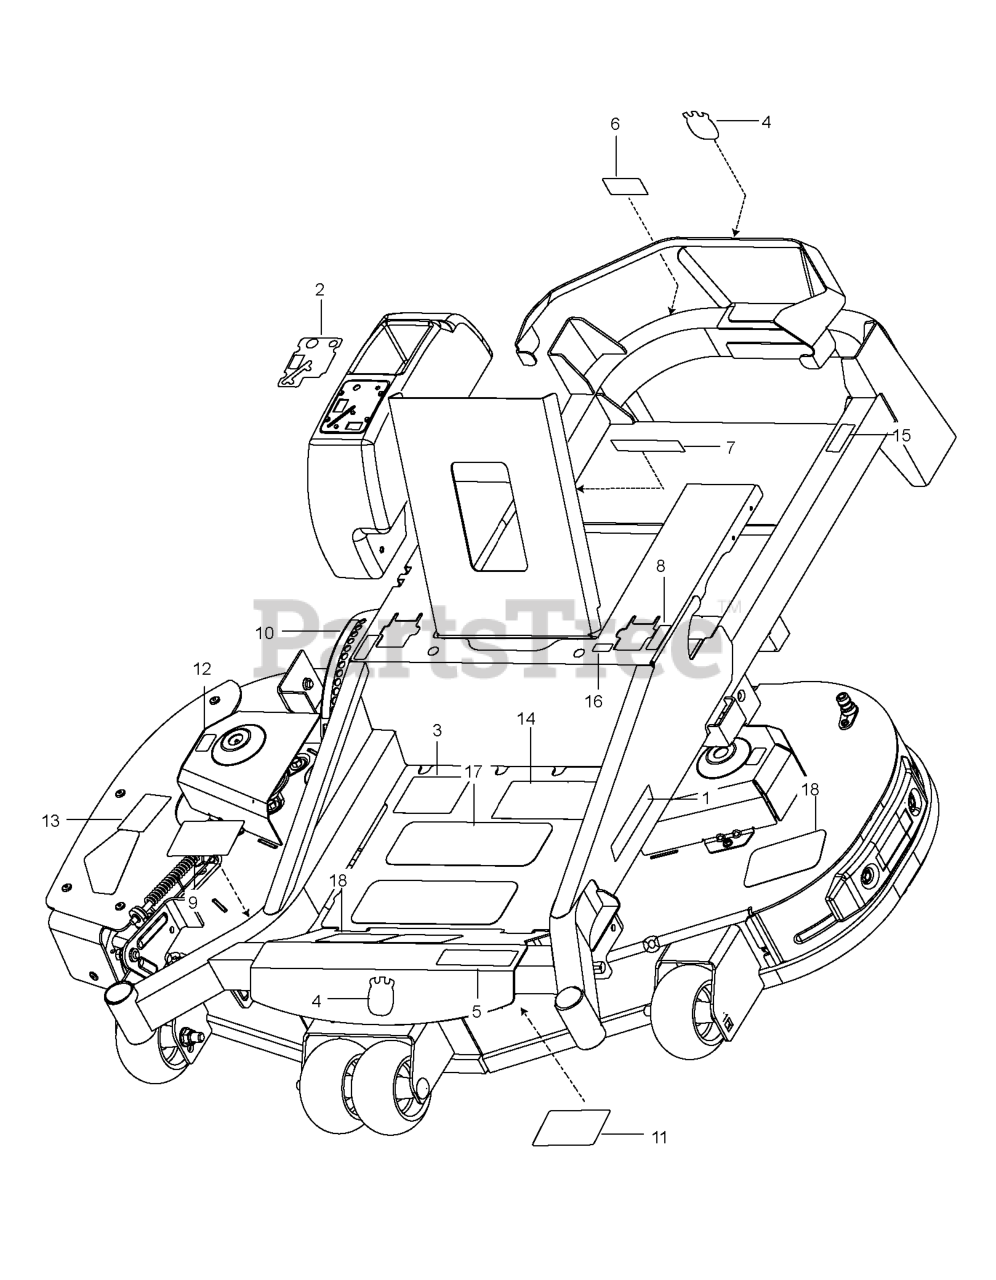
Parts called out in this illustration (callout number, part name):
1	RP.DECAL.BADGE.170MM.TEXTLOGO
2	DECAL, CONSOLE HUS
3	DECAL.ZTR.STRTNGINST.REMOTECHK
4	DECAL.AUGER.HUSQ.CROWN.SNOW
5	DECAL.MZ48
6	DECAL, BELT DRIVE
7	EURO DECAL-BATTERY WARNIN6
8	DECAL.ZTR.MOTCONTRL.SYMBOL.HUS
9	DECAL, BELT ROUTING
10	DECAL, HEIGHT ADJUST
11	DECAL, SERVICE
12	DECAL.DECK.CLEARCUT.NOSTEP
13	DECAL.TRACT/ZTR.DECKWARN.HUSQ
14	DECAL.ZTR.WARNING.SMARTIGNITIN
15	DECAL, WARNING SPARK ARRESTOR
16	DECAL.STR.S.T.SYSMBOLONLY.2014
17	ANTI-SKID PAD
